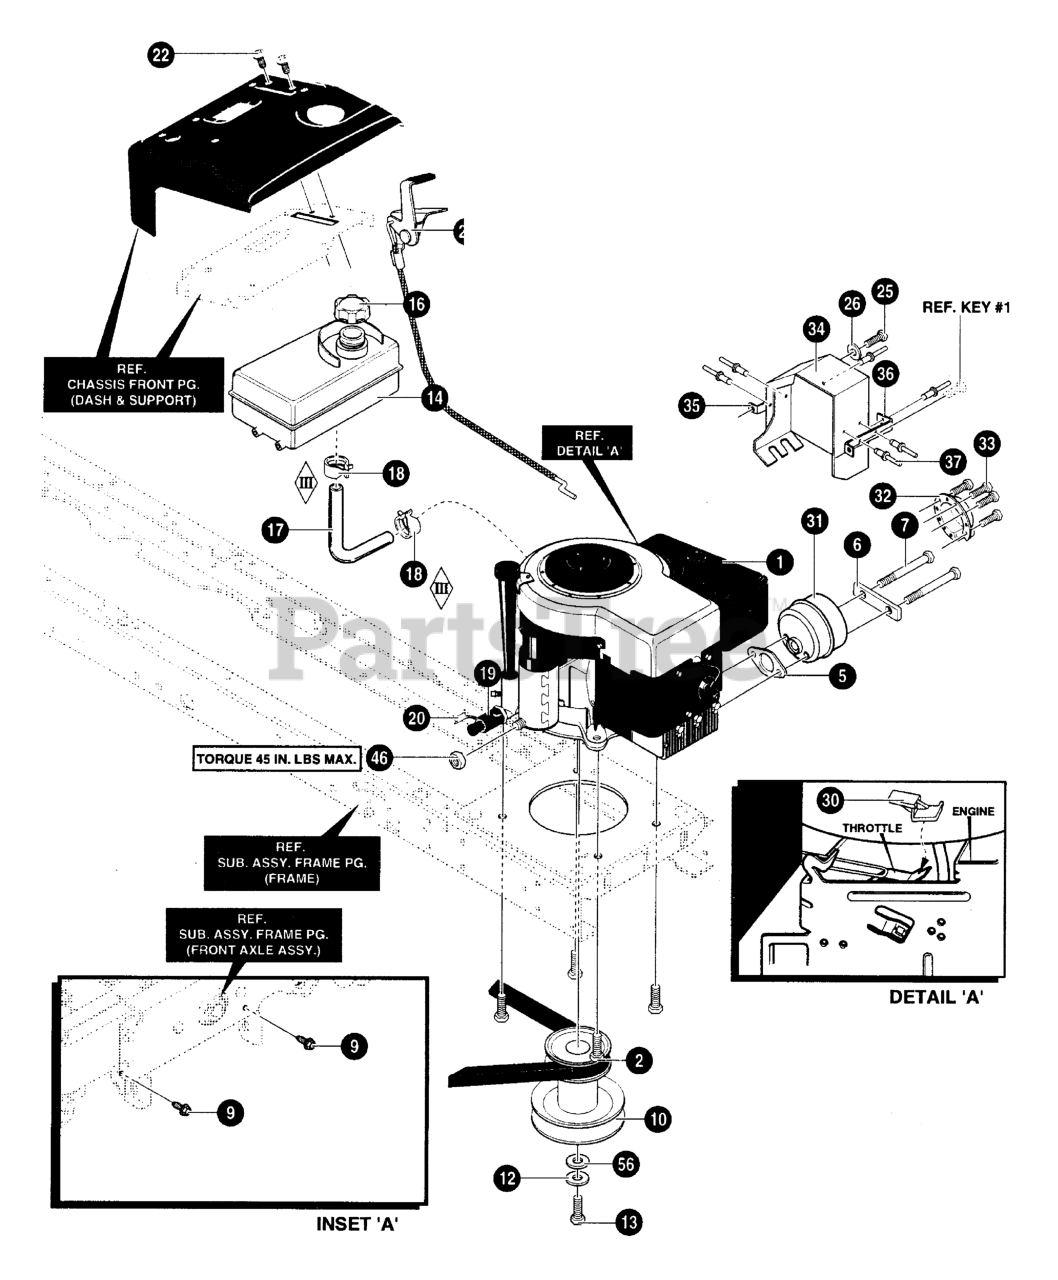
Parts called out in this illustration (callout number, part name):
1	ENGINE
2	SCREW, 3/8-16 x 1.25
5	GASKET, Exhaust
6	SCREW, LOCK
7	SCREW, 5/16-18 x 4.125
9	SCREW, 5/16-18 x 0.75
10	STACK PULLEY ASSY.
12	WASHER, SPLITLOCK
13	SCREW, 7/16-20
14	FUEL TANK
16	FUEL CAP
17	TUBING, 25 X.50
18	CLAMP, FUEL LINE
19	OIL DRAIN VALVE ASSEMBLY
20	CAP, OIL DRAIN VALVE
21	THROTTLE CONTROL
22	SCREW, #8-16 X.38
25	SCREW, 1/4-20 X.50
26	WASHER (18X32)
30	SPEED CLIP
31	MUFFLER
32	DEFLECTOR EXHAUST
33	SCREW, #8-32X .38
34	HEAT SHIELD
35	L-BRACKET
36	L-BRACKET
37	POP-RIVET
46	NUT, 1/4-20 REGHEXJAM
56	WASHER, FLAT .480X1.00X.25
